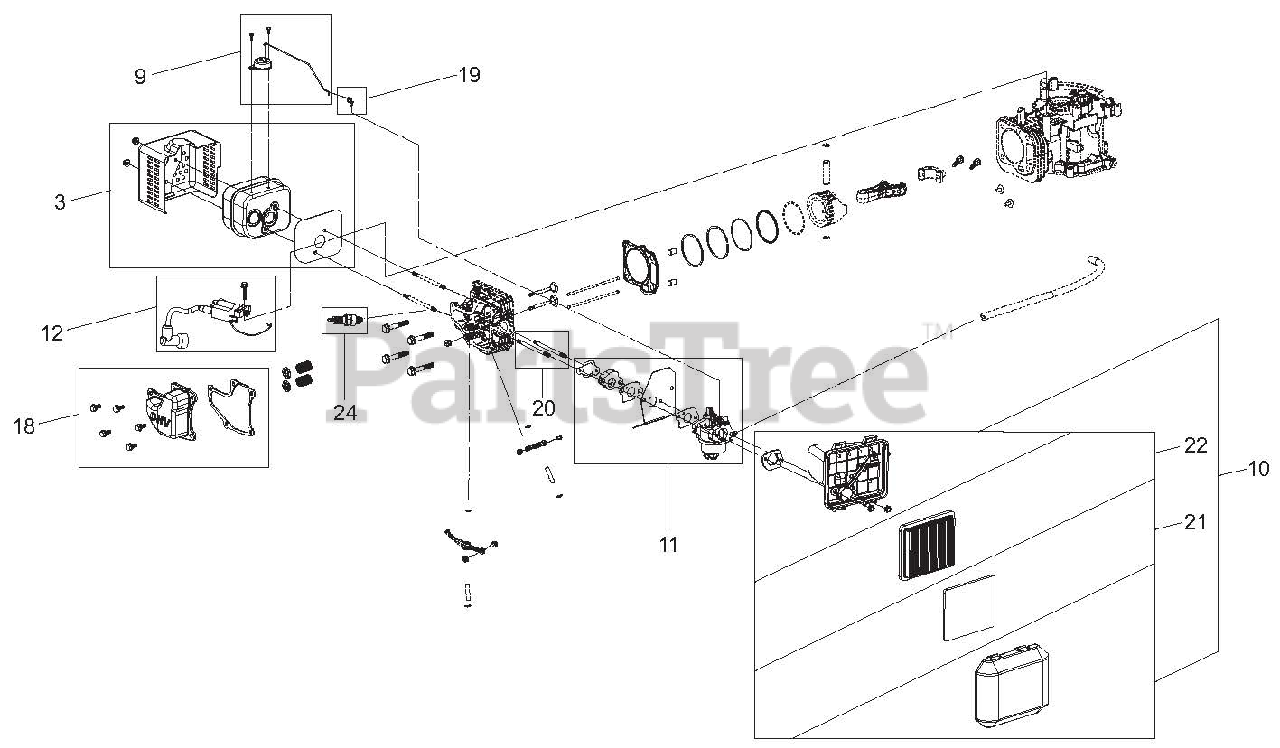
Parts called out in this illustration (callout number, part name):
3	KIT, MUFFLER AND SHIELD - SVC
9	KIT, THERMAL CHOKE CONTROL-SVC
10	KIT, AIR CLEANER ASM - SVC
11	KIT, CARBURETOR COMPLETE - SVC
12	KIT, IGNITION COIL - SVC
18	KIT, VALVE COVER - SVC
19	LOCK, THROTTLE - SVC
20	STUD, INTAKE - SVC
21	ELEMENT, AIR CLEANER
22	FILTER, AIR - LONCIN 160CC
24	SPARK PLUG, LONCIN 160CC
